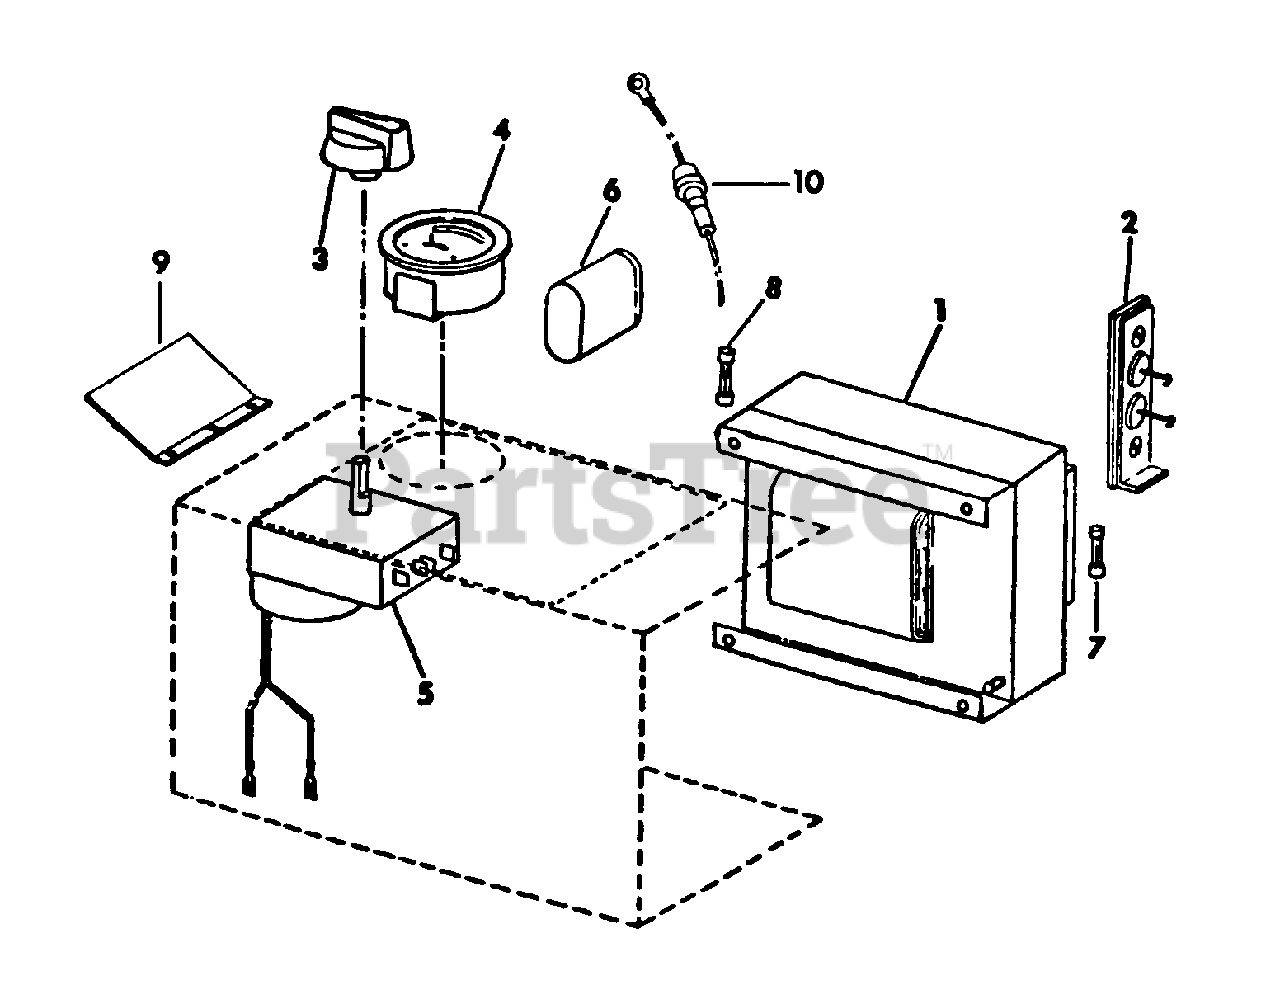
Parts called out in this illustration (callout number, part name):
1	TRANSFORMER ASSY
2	HEAT SINK ASSY
7	FUSE, AGC-10 AC
8	FUSE, AGC-20 DC
9	HOLDER, FUSE
10	RETAINER, CORD
